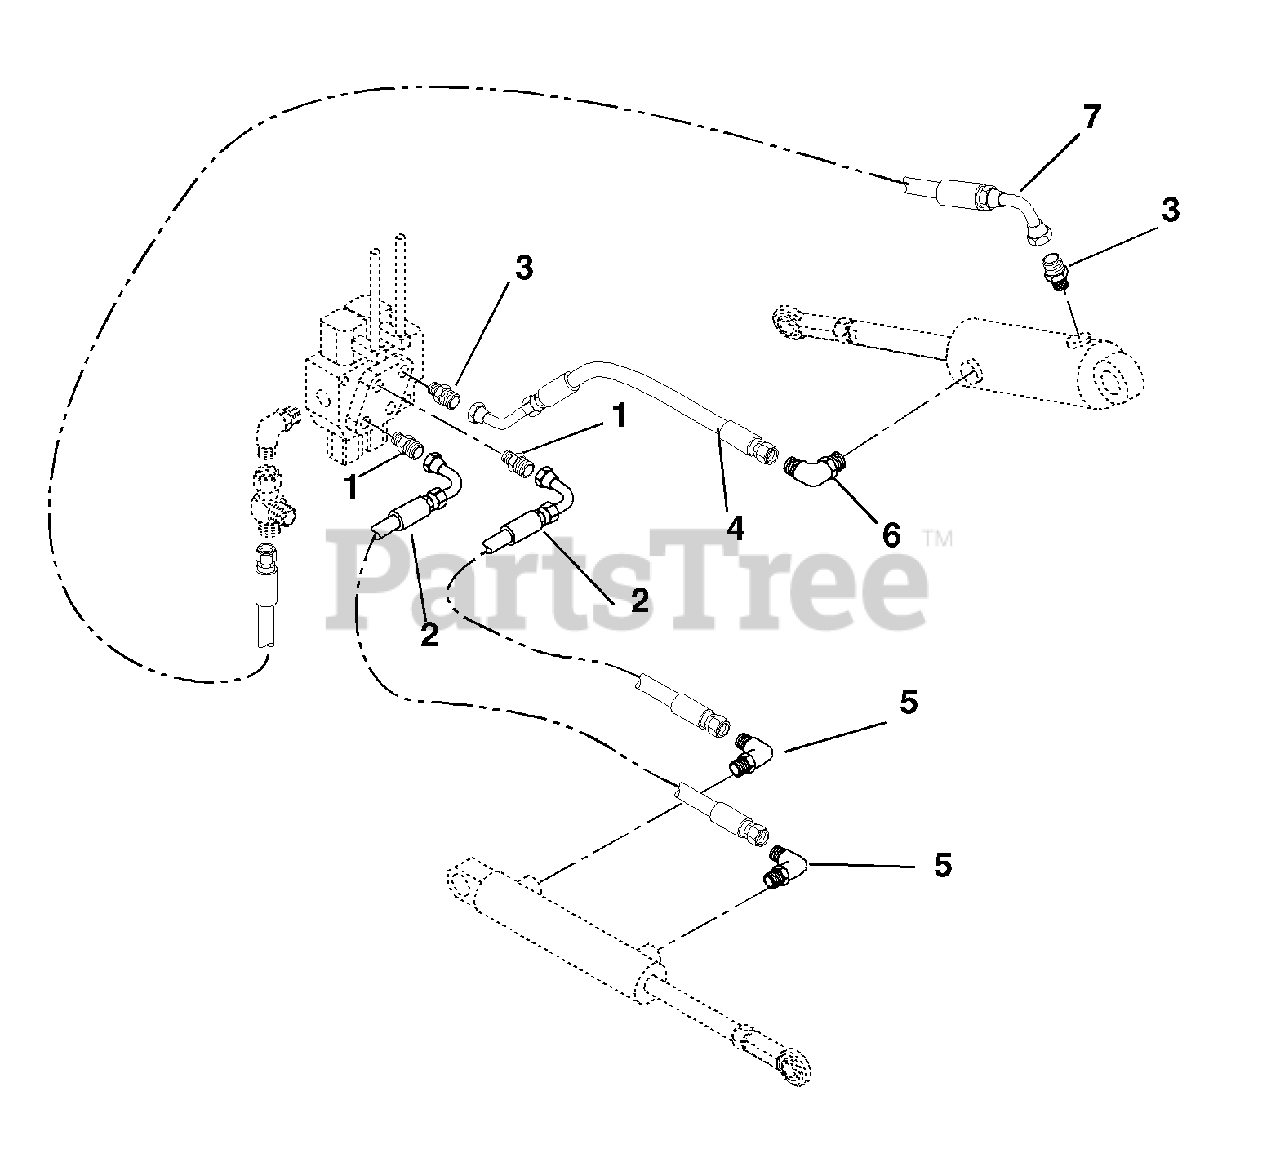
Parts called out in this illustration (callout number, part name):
1	Fitting, Hydraulic
2	Hose, Hydraulic
3	Fitting, Hydraulic
4	Hose, Hydraulic
5	Fitting, Hydraulic
6	Fitting, Hydraulic
7	Hose, Hydraulic
